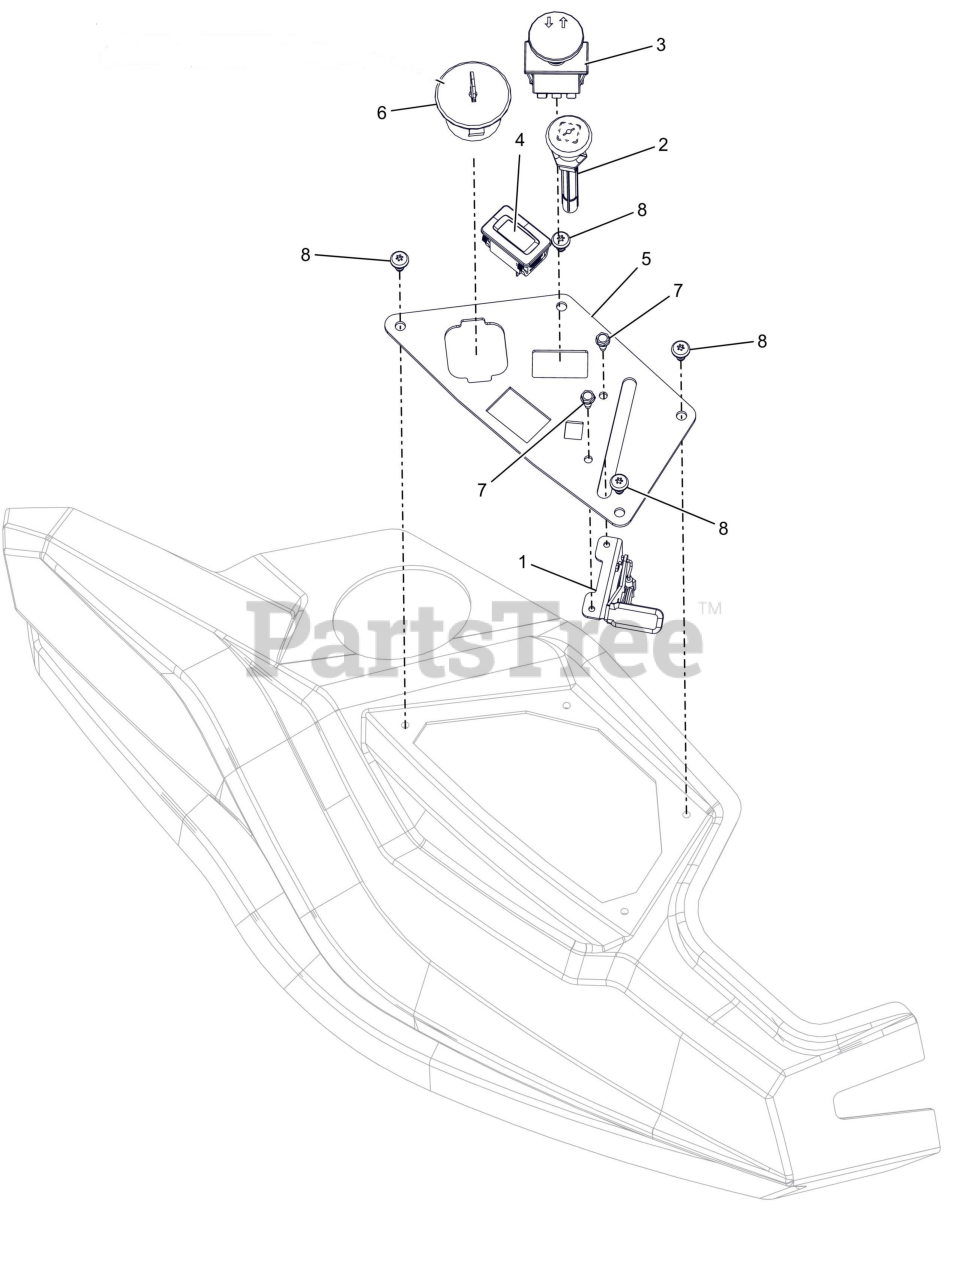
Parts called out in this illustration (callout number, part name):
1	CABLE, THROTTLE
2	CABLE, CHOKE (SNAP IN)
3	SWITCH, CLUTCH (YELLOW)
4	HOUR METER
5	PANEL, CONTROL (ORANGE)
6	KEYSWITCH-IGNITION 3 POS
6	KEY, IGNITION
7	SCR,TAP #10-24X.50 HWH TR ZCC
8	SCR-PAN .25-15X.50 6L H/LZB500
